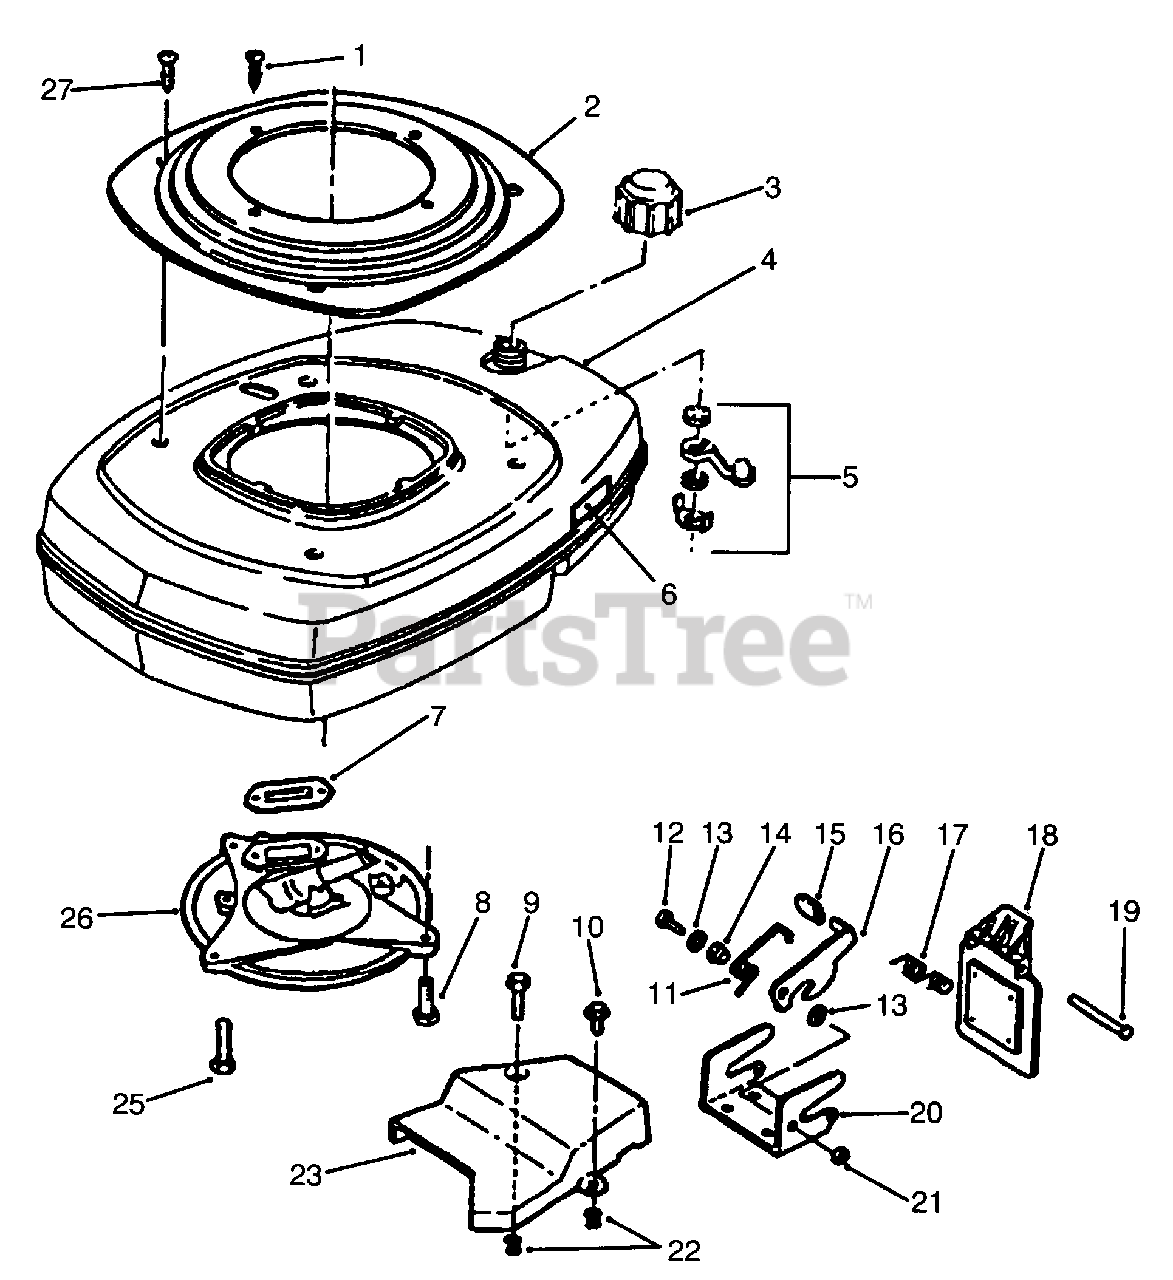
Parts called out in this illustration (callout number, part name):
1	Screw-Mount, Starter
2	Assembly-Base, Starter
3	Assembly-Cap, Fuel (Incl. following 2 items)
4	Asembly-Shroud & Tank (Incl. Ref. #5)
5	Assy.-Fuel Shut Off
7	Gasket-Exhaust
8	Screw-Muffler Plate to Hsg.
9	Screw-Hex. Hd.
11	Spring-Latch
14	Spacer-Stepped
15	Knob-Latch, Bag
16	Latch-Bag
17	Spring-Door
19	Rod-Pivot, Door
20	Plate-Hinge
21	Nut-Lock
22	Grommet-Cover, Belt
23	Cover-Belt
26	Plate-Muffler
27	Screw
